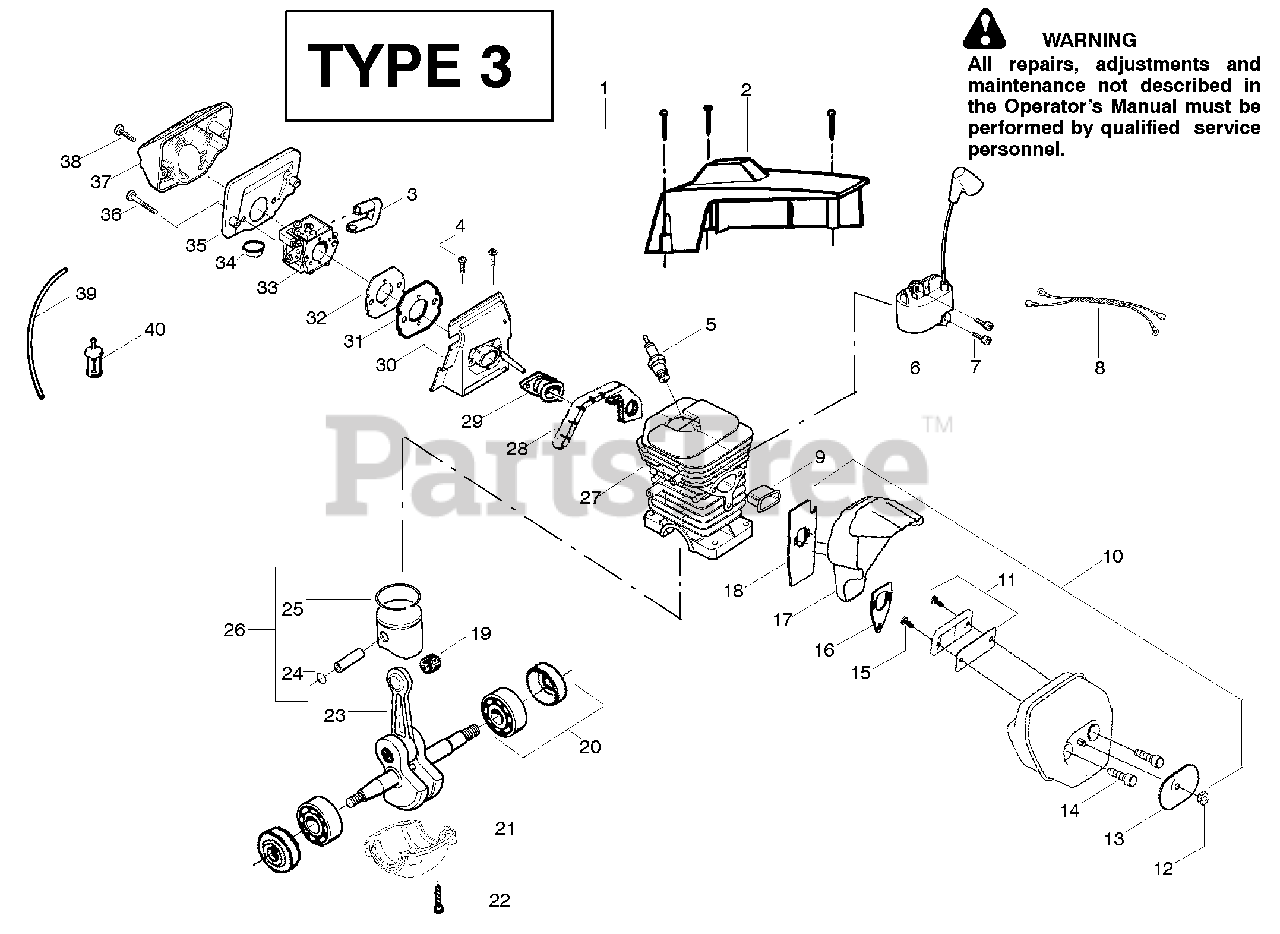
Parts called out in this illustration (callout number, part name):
2	Kit-Cylinder Shield
3	Grommet -Carb.
5	Spark Plug (RCJ-7Y)
6	Module-Ignition
8	Assy-Switch Wire
9	Insulator-Heat
10	Kit-Muffler
11	Kit-Spark Arrestor
12	Nut-Brass
15	Screw-Spark Screen
16	Gasket-Muffler
17	Assy-Muffler Backplate
18	Backplate - Alum.
19	Bearing-Piston Pin
20	Assy-Bearing & Seal
21	Cap-Crankcase
23	Assy-C’shaft & Rod
24	Retainer-Piston Pin
26	Kit-Piston
27	Assy-Cyl/Crankcase
28	Seal-Super Clean
30	Kit-Carb.-Adapter
31	Intake Plate-Carb
33	Kit-Carburetor (WT-610)
35	Filter-Air (Bottom)
37	Filter-Air (Top)
39	Kit-Fuel Line (Small)
40	Assy-Fuel Pick-up
